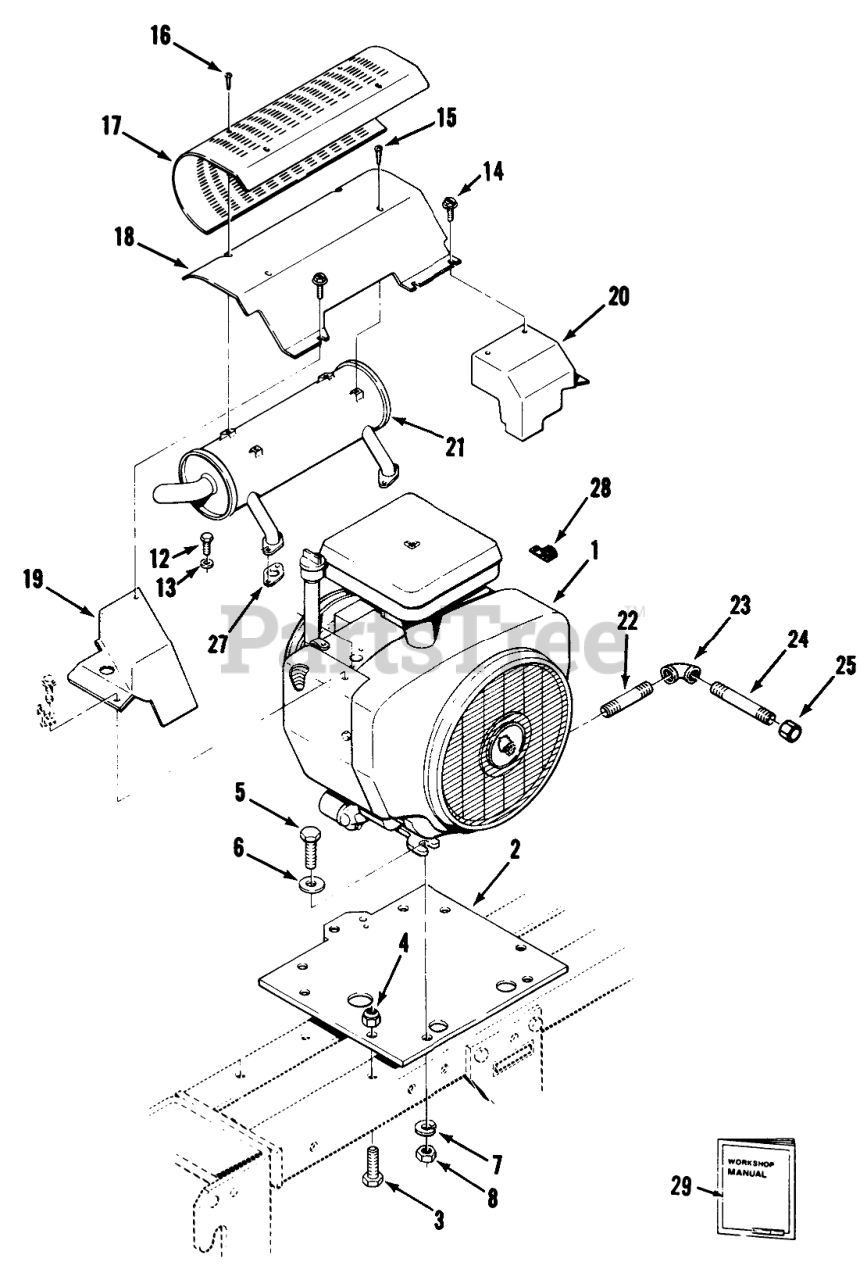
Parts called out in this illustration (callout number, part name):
1	Engine-TORO Power Plus-20HP P220G-I/10956C 520-8
2	PLATE-ENGINE B
3	Bolt
4	NUT
5	BOLT
6	Washer
7	LOCKWASHER
8	Nut
12	Bolt
13	Lockwasher
14	Bolt
15	Screw
16	SCW 10-24 STAINLESS
17	SHIELD
18	Air Deflector
19	LH Exhaust Cover
20	RH Exhaust Cover
21	MUFFLER-EXHAUST
22	Pipe
23	ELBOW 3/8 90 DEG
24	PIPE-NIPPLE 3/8 X 4"
25	Cap
27	Exhaust Gasket
28	CLIP
29	Manual-Toro Power Plus Service
